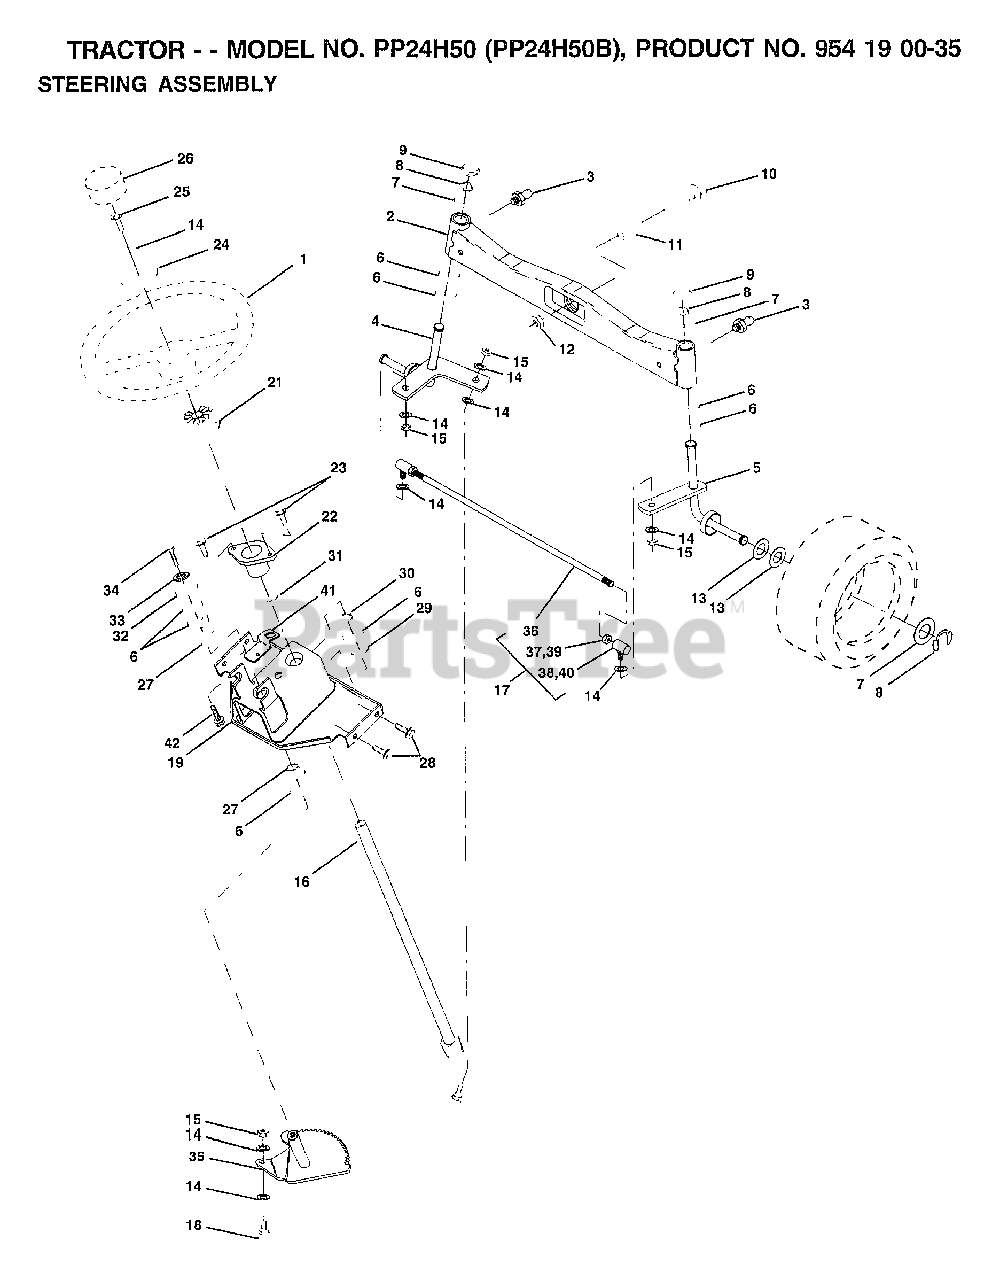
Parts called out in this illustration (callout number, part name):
3	ZERK M
4	SPINDLE ASM LH
5	SPINDLE ASM RH
6	WASHER .T
7	WASHER
8	RING
9	CAP
10	BOLT
11	SPACER BEARING
12	"NUT-LOC,FLANGE LT"
13	WASHER
14	LOCKWASHER
15	GRIPCO NUT
16	SHAFT.STEER.VGT
17	ROD.ASM.TIE.BALL
18	DRAGLINK.BALL.JOI
19	SUPPORT ASM-STEER
21	ADAPTER LT
22	"BUSHING,STEERING"
23	"SCREW-TT,10-32 FL"
24	WASHER
25	BOLT
26	"INSERT,STR WHEEL"
27	COL. SRTG. BEAR.
28	SCREW
29	"FLANGE GT, BEAR."
30	KLIP RING
31	BUSHING.NYLINER.
32	WASHER
33	LOCKWASHER
34	BOLT
35	GEAR.ASM.SECTOR.
37	NUT
38	JOINT.RH
39	NUT
40	JOINT.LH
41	"BRKT-SW, INTER"
42	SCREW LT
